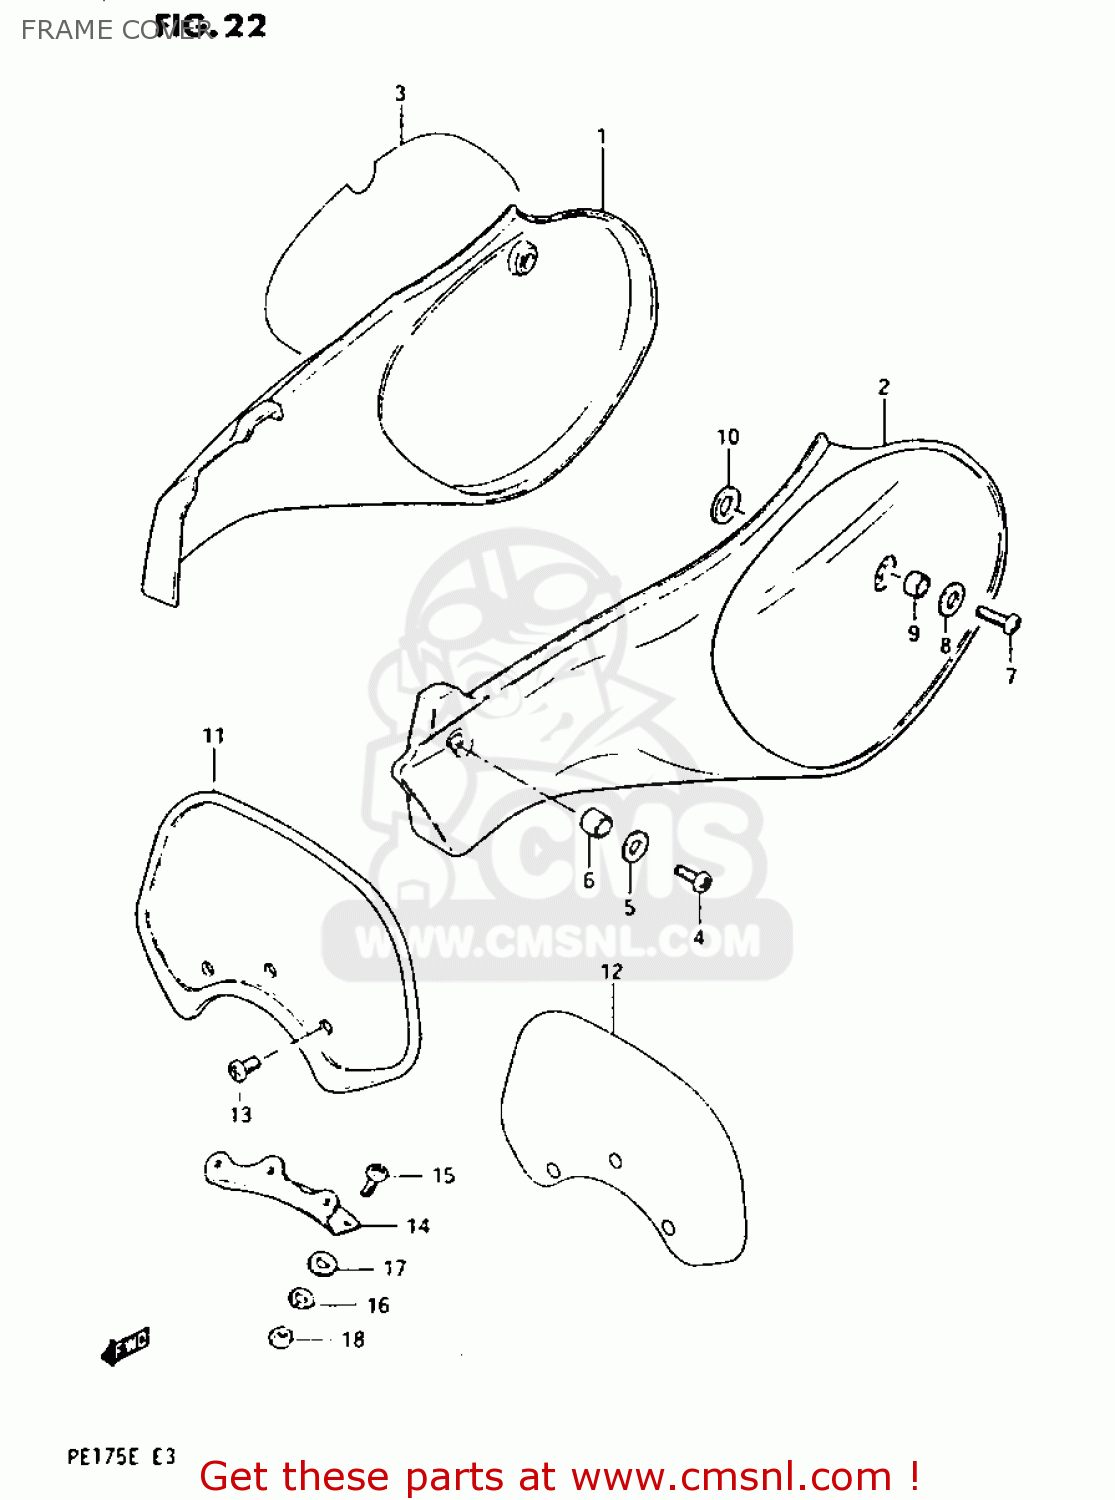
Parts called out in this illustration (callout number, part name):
1	COVER,FRAME,RIGHT
2	COVER,FRAME,LEFT
3	EMBLEM,NBR PLATE
4	SCREW
5	WASHER
6	SPACER (6.1X8X12)
7	SCREW
8	WASHER
9	SPACER
10	GASKET
11	PLATE,FRONT NUMBER
12	EMBLEM,FRONT NUMBER PLATE
13	SCREW
14	BRACKET FR NUM PLATE
15	SCREW
16	LOCK WASHER
17	WASHER
18	NUT
